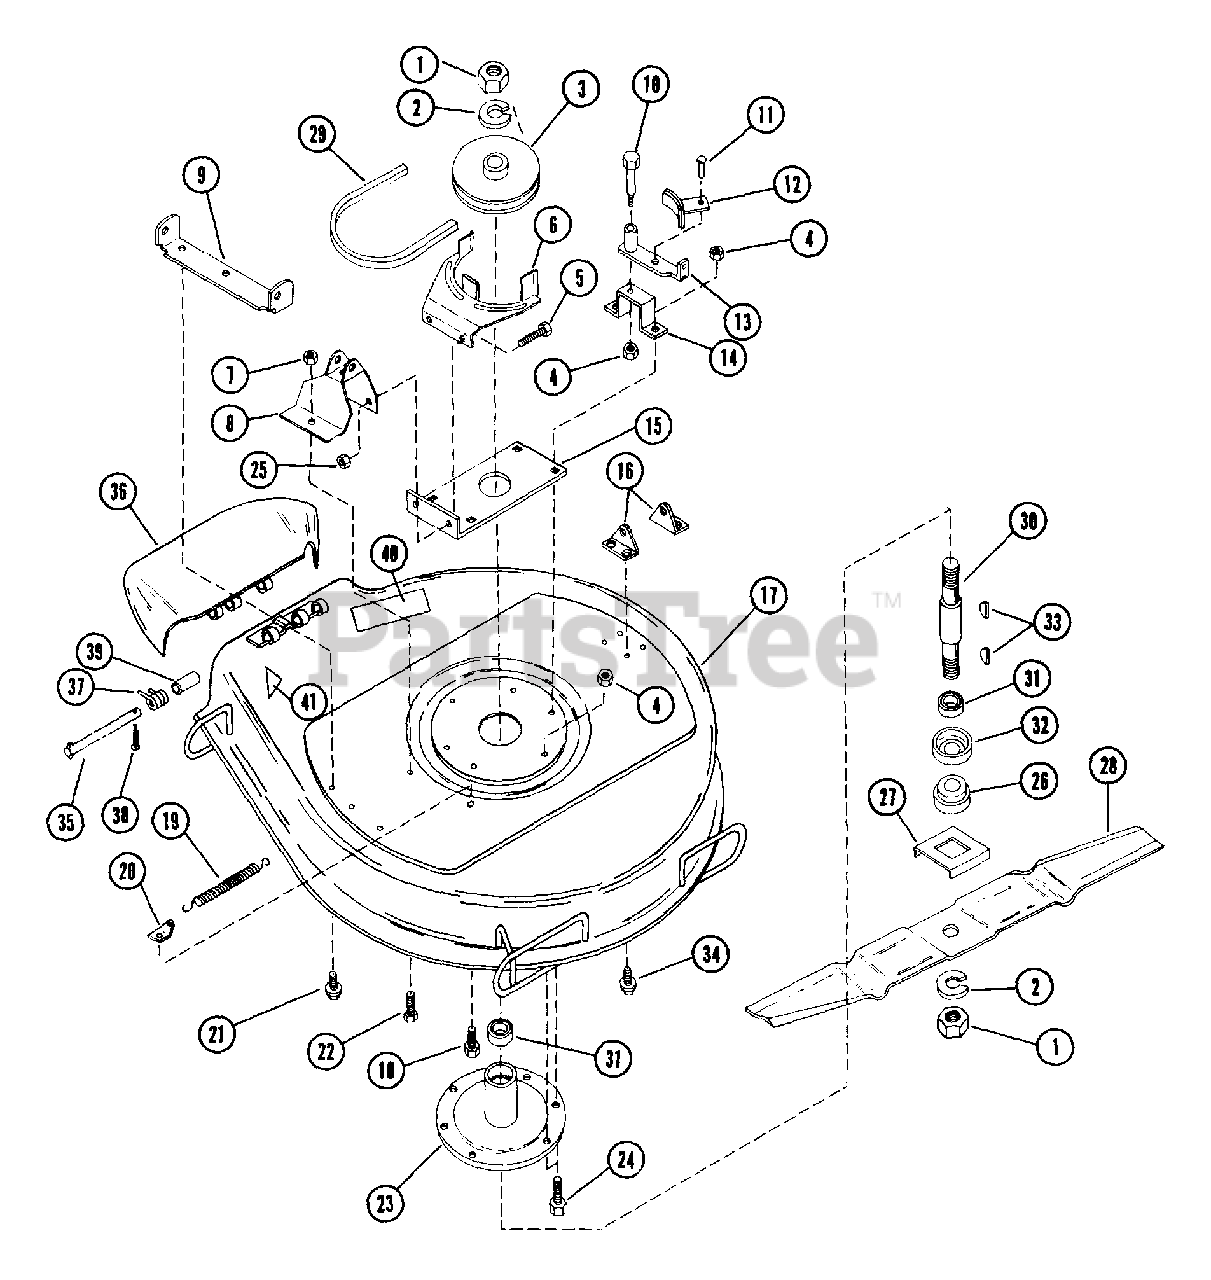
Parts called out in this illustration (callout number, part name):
1	NUT-JAM .75-10 PL
2	WSHR-LK .750X.188 MED PL
3	MOWER SHEAVE
4	NUT-LK-CTR .375-16 GR A PL
5	BLT-SERHFWH .31-18X.75 PL
7	NUT-LK .312-18 GR A PL
8	BRACKET
9	FRONT MOUNTING BRACKET
10	SHOULDER BOLT .50 X 1.75
11	RVT .25X.50 RH ST
12	BLADE BRAKE
14	BLADE BRAKE SUPPORT
16	REAR MOUNTING BRACKET
17	PAN ASSEMBLY
18	BLT-SERHFWH .25-20X.50 PL
19	SG-TENS .072X.51X5.31 WLD 25
20	BRAKE CLIP
21	BLT-SCRHFWH .38-16X.50 PL
22	BLT-HEX .31-18X.50 PL GR2
23	SPINDLE HOUSING
24	BLT-HEX .38-16X1.00 PL
25	NUT-FLG. .312-18 PL
26	RETAINER HUB
27	BLADE TRAY
28	MOWER BLADE
29	V-BELT, 5L-RAW EDGE
30	MOWER SPINDLE
31	BRG-BALL .751X1.78X.61
32	BEARING SLINGER
33	KEY-WDRF .188X.75X.313 SAE 9
34	BLT-SERHFWH .31-18X.50 PL
35	CLEVIS PIN
36	PAN CHUTE EXTENSION
37	SG-TORS .095X.50X 1.0
38	PIN-COTR .09X.75 PL
39	BSHG-SLV .334 X .502 X 1.437
40	MOWER CAUTION LABEL
41	SAFETY LABEL
